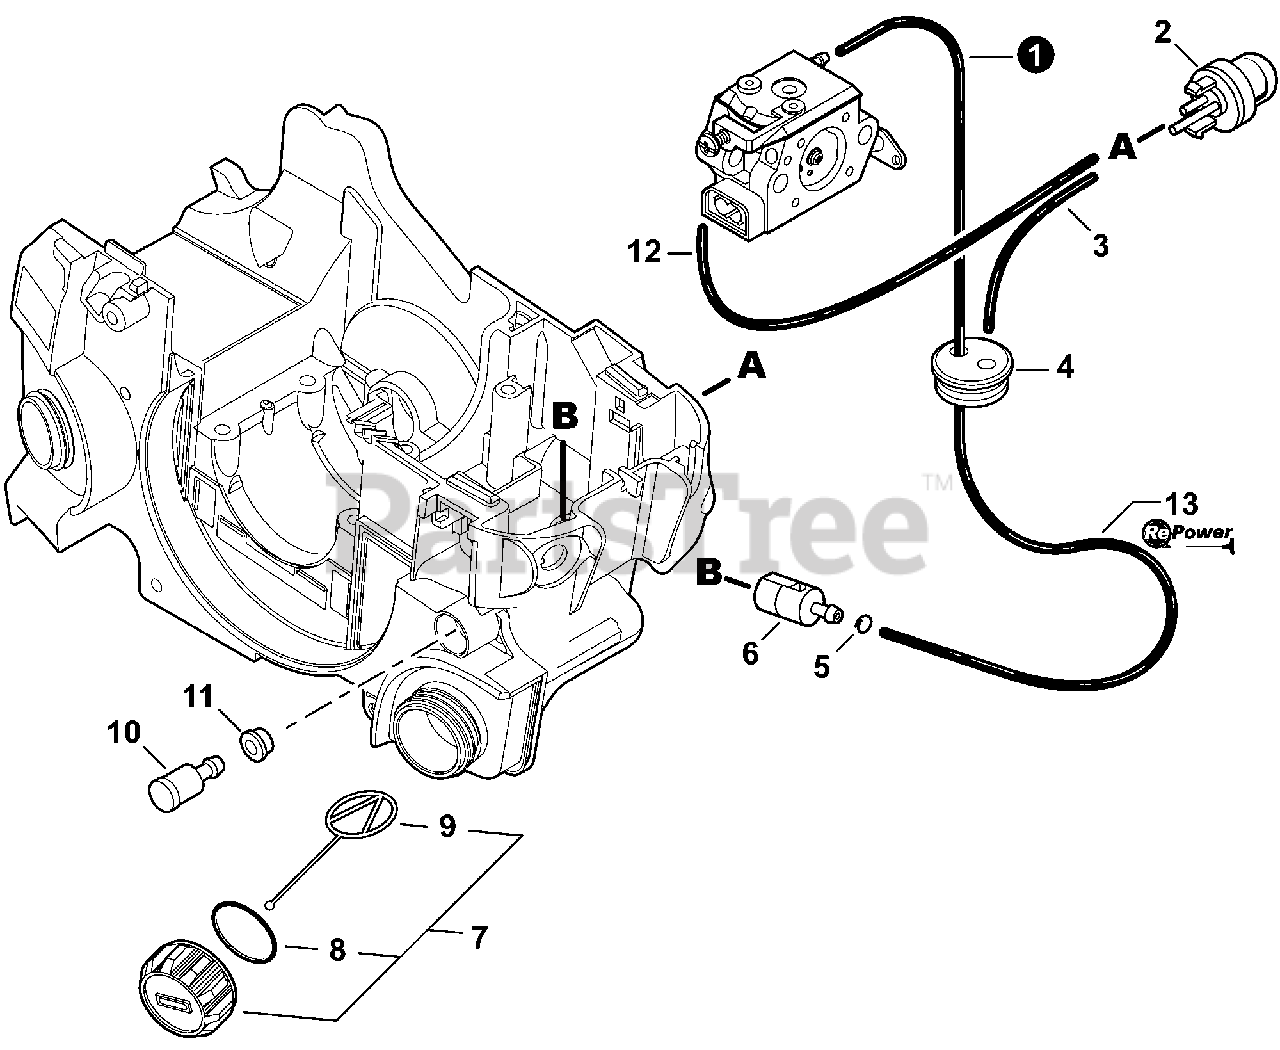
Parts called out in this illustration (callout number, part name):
1	PIPE, FUEL 3×5×230 BLACK
2	BULB, PURGE
3	PIPE, FUEL 2.4×5×80 BLACK
4	GROMMET, FUEL
5	CLIP 6 MM
6	FILTER, FUEL
7	CAP ASSY, FUEL
8	O-RING 22
9	CONNECTOR, CAP L= 60 MM
10	VENT ASSY
11	GROMMET, FUEL
12	PIPE 2.4×5×125 BLACK
13	BULK PIPE - 3×5 MM BLACK (4 PIECES×2 M)
